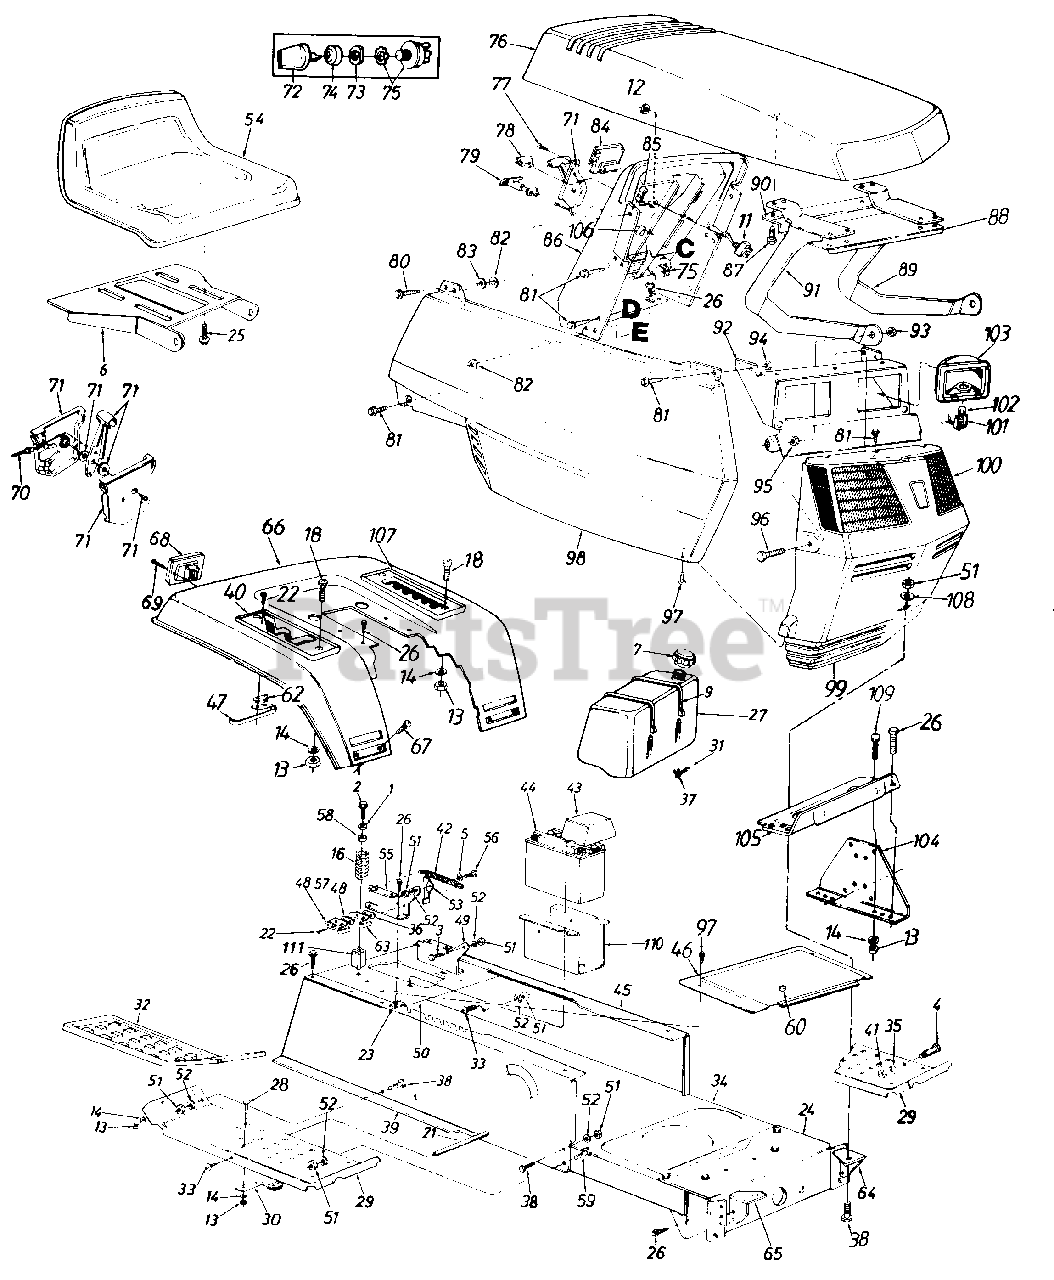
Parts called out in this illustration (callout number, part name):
1	Fl-Wash. .344" I.D. x .875"
2	Hex Wash. Hd. Tap Scr. 5/16-18 x 3.25" Lg.
3	Shld. Bolt.437" Dia. x .162"
4	Shld. Bolt .50" Dia. x .84"
5	Spr-Wash. .445" I.D. x .75
6	Seat Pivot Bracket
7	Fuel Cap
9	Tie Strap
11	Toggle Switch
12	Hex Nut 1/2-27 Thd.
13	Hex Nut 1/4-20 Thd.
14	L-Wash 1/4" I.D.
16	Compresslon Spring
18	rruss Mach. Scr. 1/4-20 x .75" Lg.
21	Running Board Rod
22	Hex Wash. Hd. AB-Tap Scr. #8 x .50" Lg.
23	Speed Nut #10Z
24	Front Pivot Brkt.
25	Hex Tap Scr. 3/8-16 x .75"
26	Hex Wash. Hd. AB-Tap Scr. 5/16 x .75" Lg.
27	Fuel Tank
28	Carriage Bolt 1/4-20 x .62"
29	Running Board
30	Blade Brake Ass'y.
31	Fuel Line
32	Rubber Foot Pad L.H.
33	Truss Mach. Scr. 5/16-18 x .75" Lg.
34	Lower Frame
35	L-Wash. 3/8" I.D.
36	Insulator Boss Plate
37	Hose Clamp
38	Hex Bolt 5/16-18 x .75" Lg.
39	Upper Frame R.H.
40	Forward/Reverse Index Brkt.
41	Hex Nut 3/8-16 Thd.
42	Extension Spring 5.31" Lg.
43	Utility Box
44	12-V Battery (275 Cold Crank Amps)
45	Upper Frame L.H.
46	Shift Cover
47	Reverse Safety Switch
48	Insulator Plate
52	L-Wash. 5/16" I.D.
53	Seat Lift Brkt.
54	Seat
56	Shld. Bolt .437" Dia. x .268"
57	Spring Switch
58	Bushing
59	Hex Wash. TT-Tap Scr. 5/16-18 x 718" Lg.
60	Snap Bushing
62	Insulator Nut Plate
63	Safety Switch (Seat)
64	Grille Mount Brkt. L.H.
65	Grille Mount Brkt. R.H.
66	Fender
67	Carriage Bolt 1/4-20 x .62" Lg.
68	Taillight
69	Truss Hd. AB-Tap Scr. #6 x .62" Lg.
70	Throttle Wire 35" Lg.
71	Throttle Control Box Ass'y.
72	Ignition Key
73	Ignition Switch Nut
74	Ignition Switch Cap
75	Ignition Switch
78	Light Switch
79	Choke Control 38" Lg.
80	Hex Wash. Hd. Tap Scr. 1/4 x .75" Lg .
81	Hex Tap Scr. 1/4-20 x .5" Lg.
82	Push Nut Fastener
83	Fl-Wash. .27" I.D. x .948"
84	Ammeter
85	Speed Nut 1/4-20 Thd.
86	Dash Panel
87	Hex Wash. Hd. B-Tap Scr. 1/4 x.62" Lg.
88	Hood Reinforcement
89	Hood Hinge L.H.
94	Hex L-Nut 1/4-20 Thd.
95	Hex Jam Nut 5/16-18 Thd.
96	Hex Bolt 5/16-18 x 718" Lg.
97	Truss Mach. B-Tap Scr. #10 x .5" Lg.
98	Side Cover R.H.
101	Twist Lock Lamp Socket
102	Lamp
103	Headlight Housing
106	Choke Retainer
107	7-Speed Index Brkt.
108	Fl-Wash. .34" I.D. x .68" O.D.
109	Hex Bolt 1/4-20 x .62" Lg.
110	Battery Tray
111	Spring Spacer
